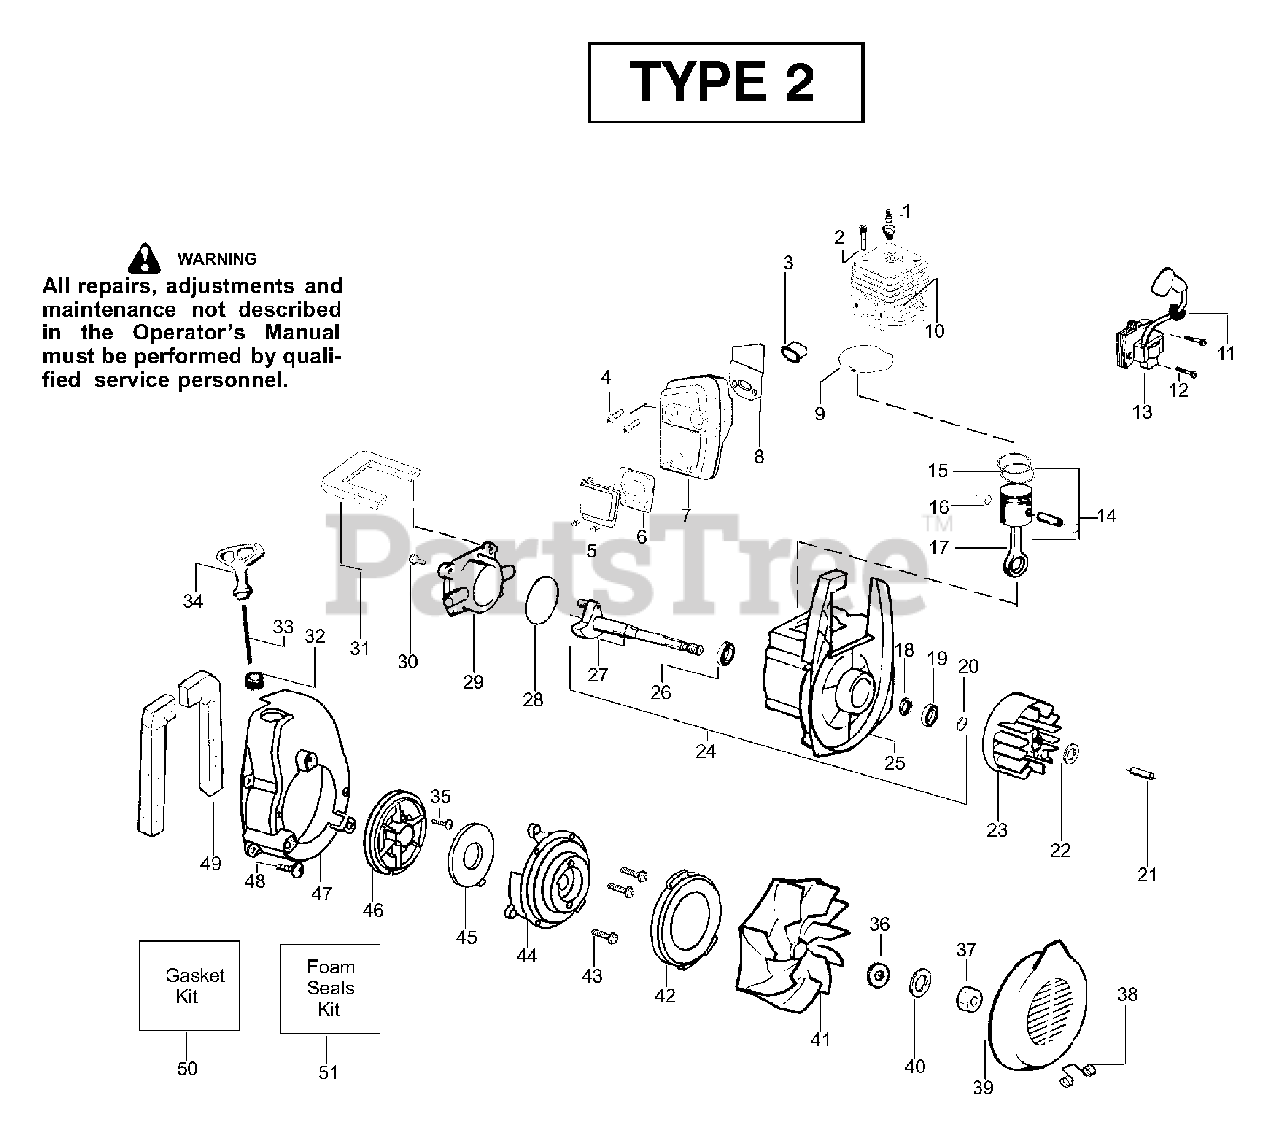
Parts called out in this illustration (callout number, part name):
1	Spark Plug (RCJ-6Y)
3	Insulator-Heat
4	Screw-Muffler-Internal
6	Kit-Spark Screen
7	Kit-Muffler
8	Gasket-Baffle (kit)
9	Gasket-Cylinder (kit)
10	Kit-Cylinder
11	Grommet-Ign. Module
12	Screw-Ignition Module
13	Ignition Module
14	Kit-Piston
15	Piston Ring
16	Retainer-Piston Pin
17	Assy-Connecting Rod
18	Kit-Crankcase Seal
19	Bearing-Outer
20	Retainer Ring-C'chaft
21	Spacer-Flywheel
23	Assy-Flywheel
24	Assy-Crankcase/Crankshaft
25	Assy-Crankcase
26	Bearing-Inner
27	Assy-Crankshaft
28	O-ring-C/case (kit)
29	Cover-Crankcase
30	Screw
31	Foam-219mm (kit)
32	Eyelet-Flange
33	Kit-Rope
34	Handle-Starter
35	Screw-Rope
36	Washer-Belleville
38	Spring-Return Cover
39	Inlet Door
40	Washer-Flat
41	Assy-Impeller
42	Seal-Ring
44	Housing-Pulley
45	Spring-Starter
46	Kit-Starter Pulley
47	Fan Housing
48	Screw
49	Foam-182mm (kit)
50	Kit-Gasket
51	Kit-Foam Seals
